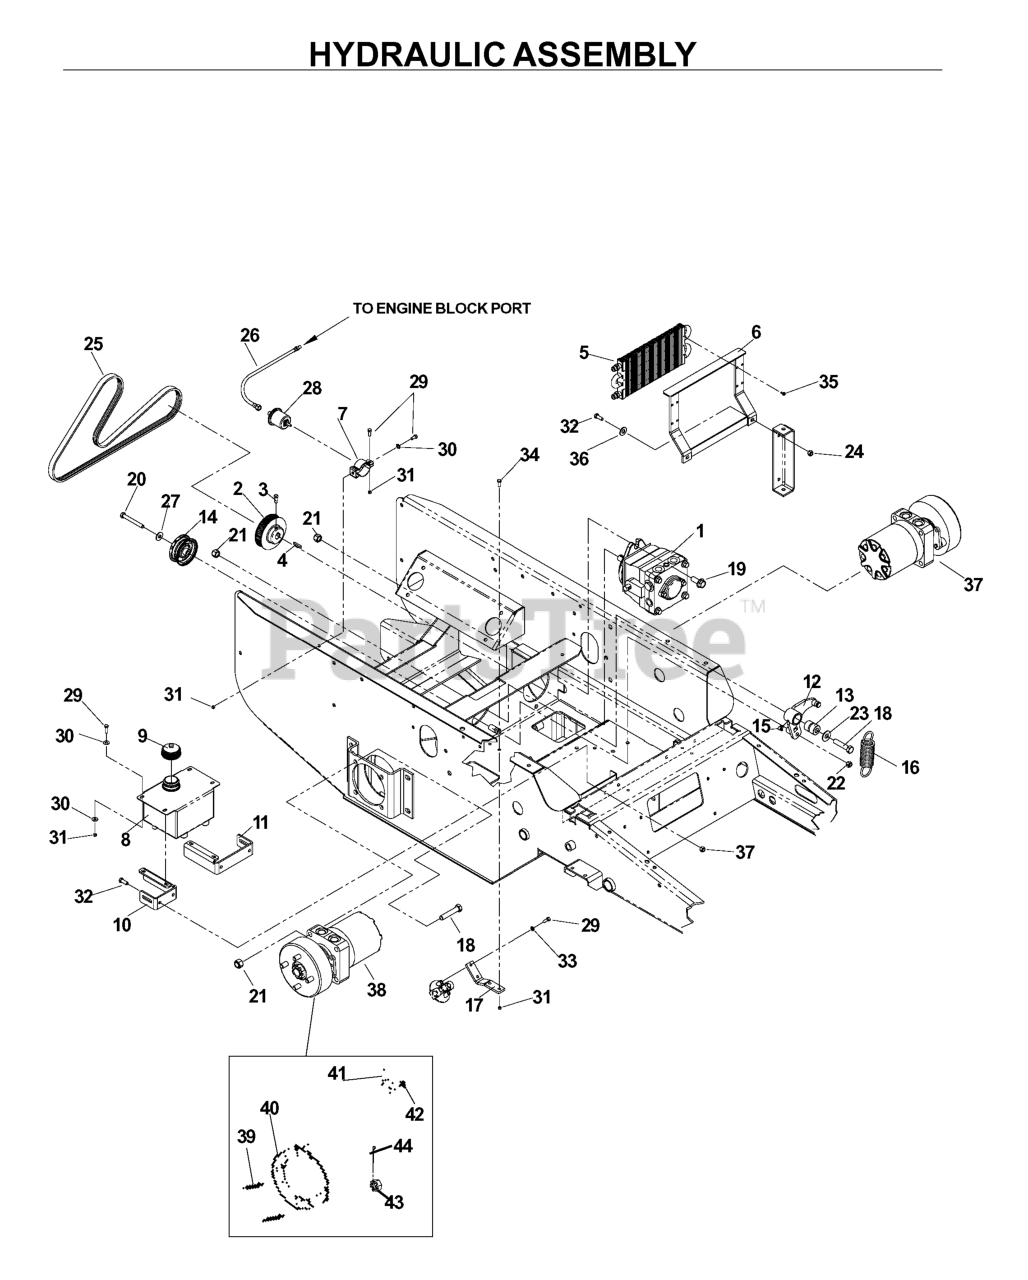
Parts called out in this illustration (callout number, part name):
1	HG_PUMP CCW RH
2	PUMP SHEAVE
3	SCREW, HEAD SET 5/16C X 3/4 SQ
4	KEY, METRIC
6	COOLER WLDMT MT
7	CLAMP-OIL SENDER
8	TANK, OIL = PAINTED
9	HYDRAULIC CAP
10	TANK MOUNT RT
11	TANK MOUNT LT
12	ARM WELDMENT
14	IDLER PULLEY
17	FILTER MOUNT - PAINTED
18	HEX SCREW 1/2-13 X 2.5" GR 5
19	HCS 1/2C X 1 1/4 SERRATED HEAD
20	HCS 3/8C X 3
21	NUT 1/2-13 HEX NYLOC ZD
22	NUT 3/8-16 NYLOC
23	WASHER 1/2 FLAT
24	NUT 5/16 NYLOC
27	WASHER 3/8 SAE FLAT
28	SENDER,OIL PRESS
29	HCS 1/4C X 3/4 HCS
30	WASHER 1/4 FLAT
31	NUT.1/4-20.HEX.NYLOC.ZD
32	HCS 5/16C X 1
33	LOCKWASHER 1/4"
34	HCS 1/4 X 1
35	HSMS #10 X 5/8
36	WASHER 5/16 FLAT
37	WHEEL MTR ASM
38	WHEEL MTR ASM, RT
39	RETURN SPRING
43	CASTLE-NUT
44	COTTER PIN
